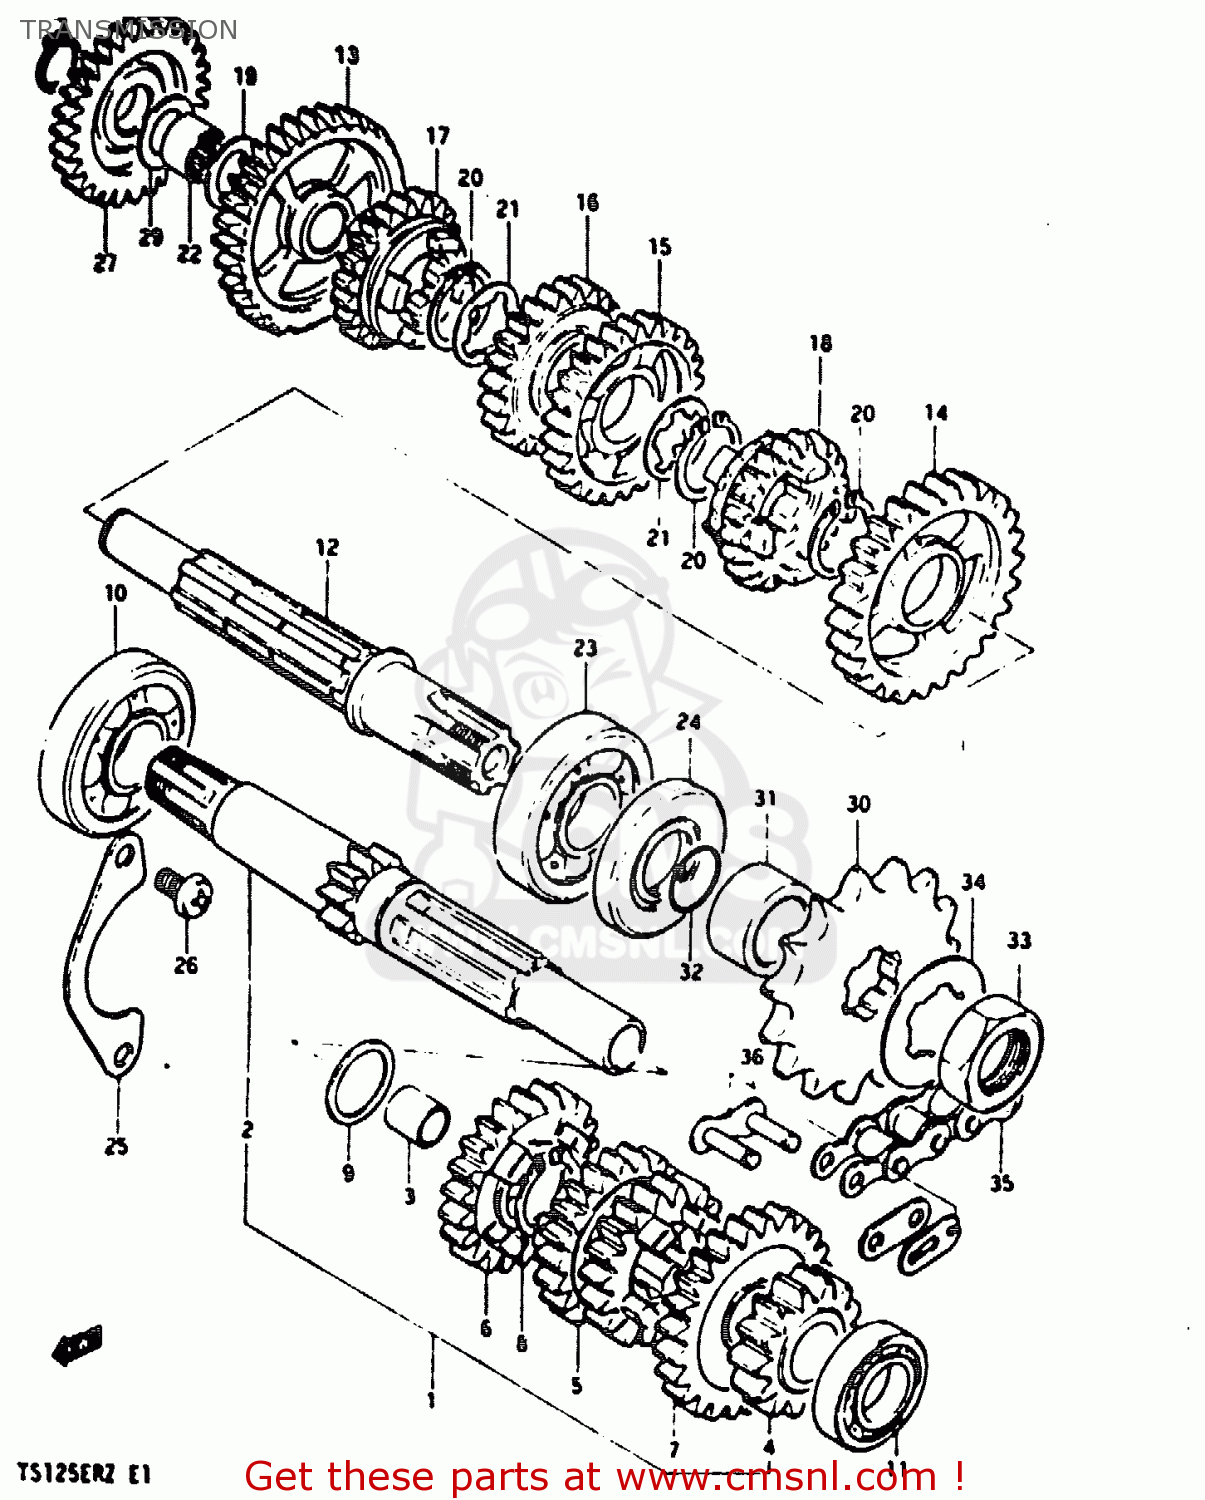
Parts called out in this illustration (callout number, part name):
1	COUNTERSHAFT ASSY
2	COUNTERSHAFT (NT:11)
3	BUSHING
4	GEAR,2ND DRIVE(NT:14)
5	GEAR, 3RD & 4TH DRIVE
6	GEAR, 5TH DRIVE (NT:23)
7	GEAR, 6TH DRIVE (NT:25)
8	CIRCLIP
9	WASHER
10	Bearing
11	BEARING
12	SHAFT,DRIVE
13	GEAR, 1ST DRIVEN (NT:34)
14	GEAR, 2ND DRIVEN (NT:26)
15	GEAR,3RD DRIVE
16	GEAR, 4TH DRIVEN (NT:23)
17	GEAR, 5TH DRIVEN (NT:22)
18	GEAR, 6TH DRIVEN (NT:21)
19	WASHER,THRUST
20	CIRCLIP
21	WASHER,LOCK
22	BEARING(15X22X12)
23	Bearing
24	SEAL,OIL(27X40X6)
25	RETAINER,CNTR SHAFT BEARING
26	SCREW 6X12
27	GEAR,KICK STARTER IDLE
28	CIRCLIP,15MM
29	WASHER,THRUST
30	SPROCKET,ENGINE(NT:15)
31	SPACER(20X27X13.1)
32	O RING(D:1,ID:19.5)
33	NUT
34	WASHER,LOCK
35	CHAIN ASSEMBLY,DRIVE
36	JOINT ASSEMBLY,CHAIN
